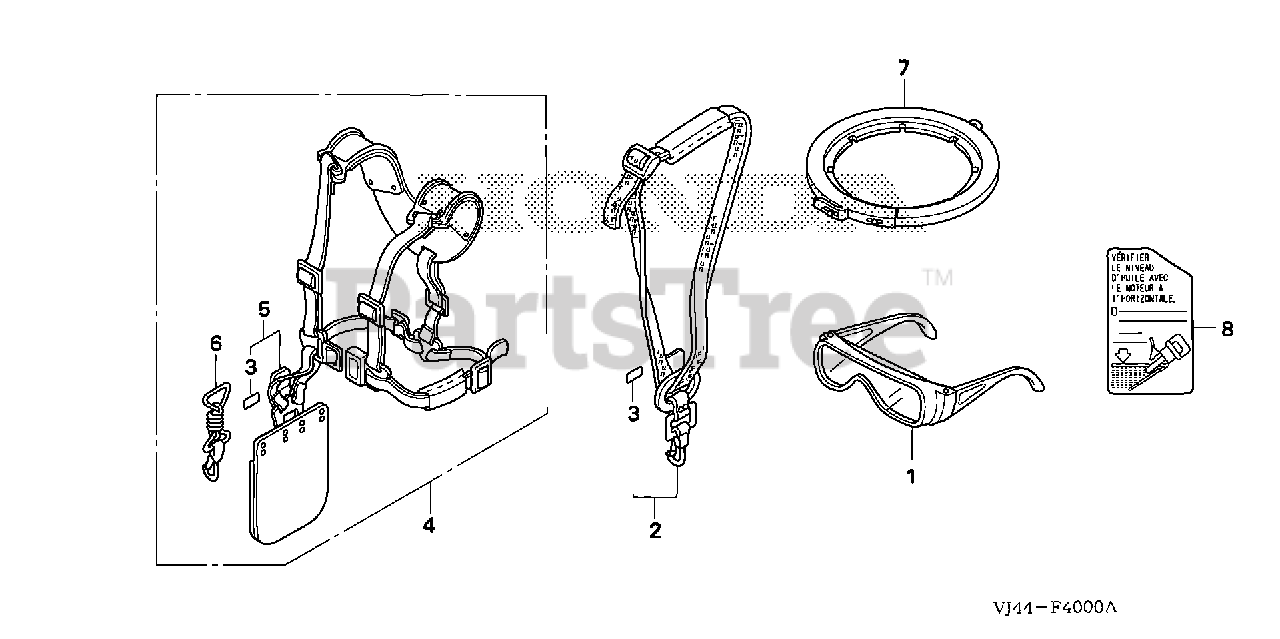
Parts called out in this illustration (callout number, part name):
1	PROTECTOR, EYE
2	BELT ASSY., SHOULDER
3	MARK, QUICK RELEASE (E)
